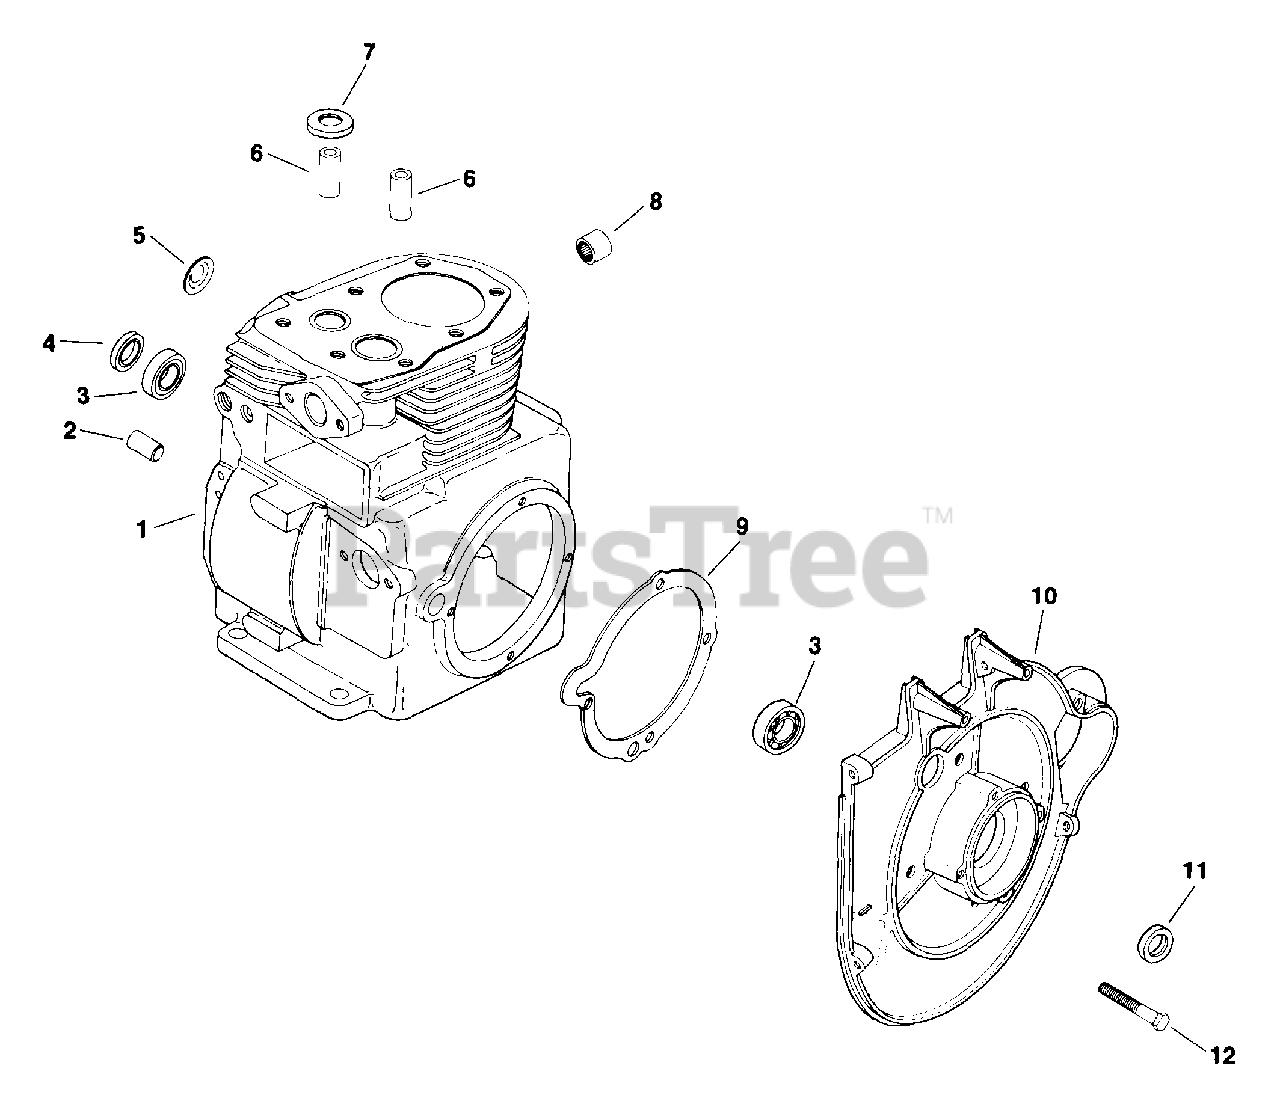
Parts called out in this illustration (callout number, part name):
1	Cylinder block
3	BEARING - DISCONTINUED
5	PLUG, WELCH EXPANSION
7	INSERT - DISCONTINUED
8	BEARING
10	PLATE - DISCONTINUED
